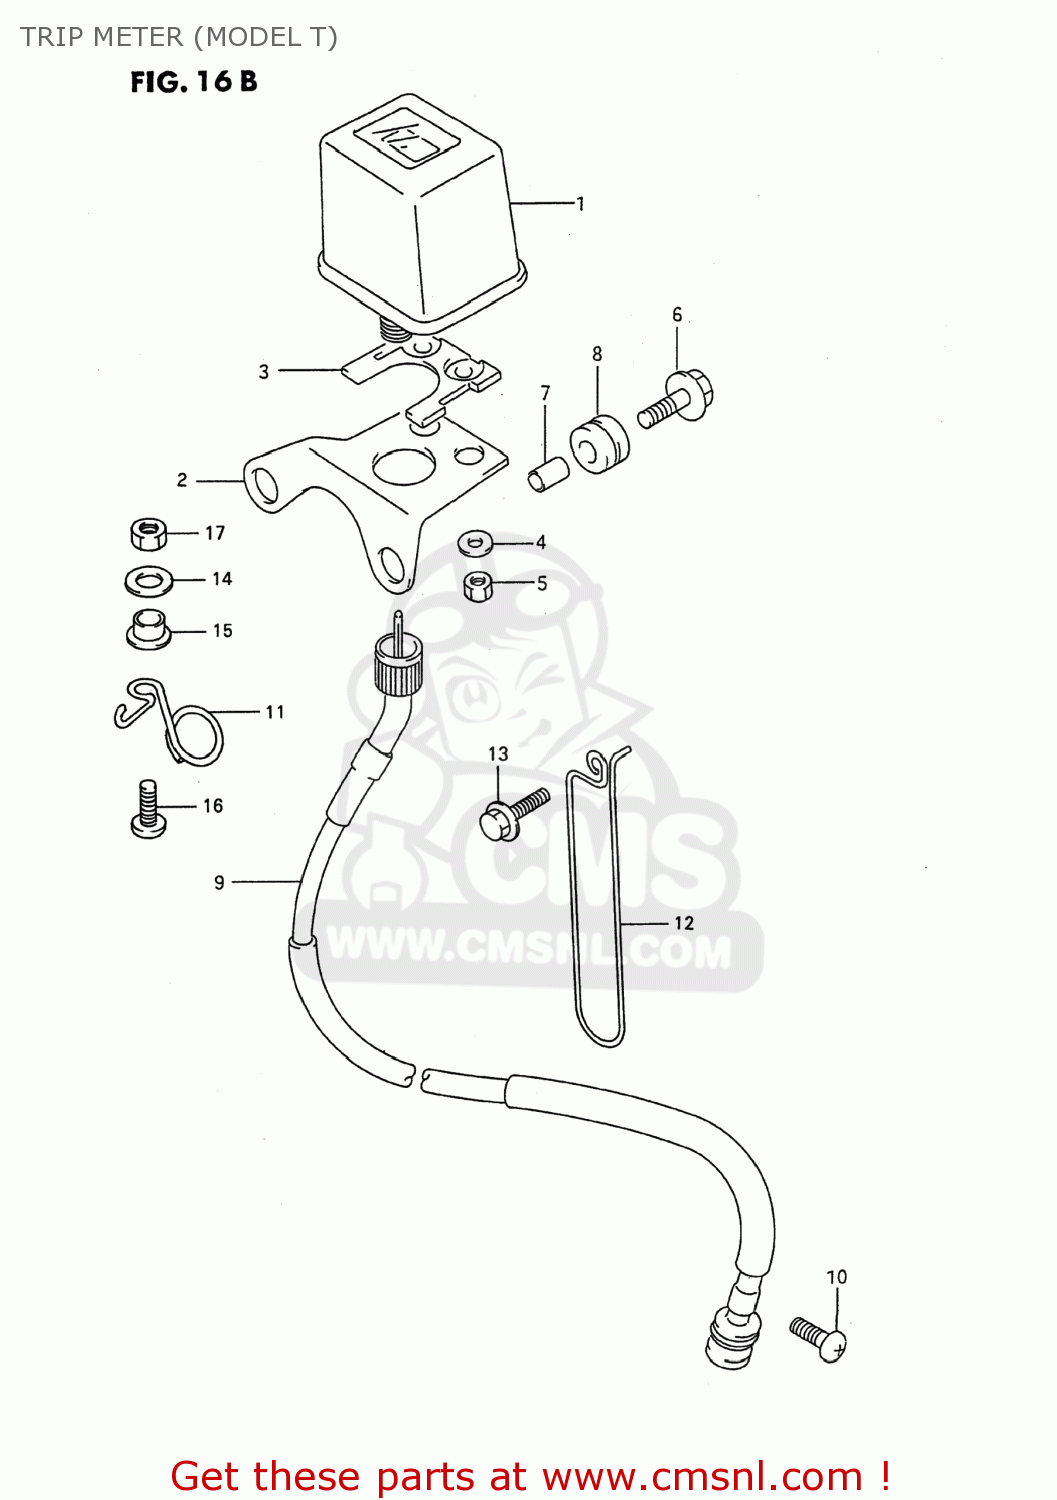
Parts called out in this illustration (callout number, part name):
1	TRIP METER
2	BRACKET
3	CUSHION
4	WASHER (4.3X13X0.80)
5	NUT
6	BOLT(6X25)
7	SPACER (6.1X8X9.5)
8	CUSHION
9	CABLE ASSY,SPEEDOMETER
10	SCREW
11	GUIDE,SPEEDOMETER CABLE
12	GUIDE,METER CABLE NO.2
13	BOLT(6X16)
14	WASHER
15	WASHER
16	SCREW
17	NUT 6MM
